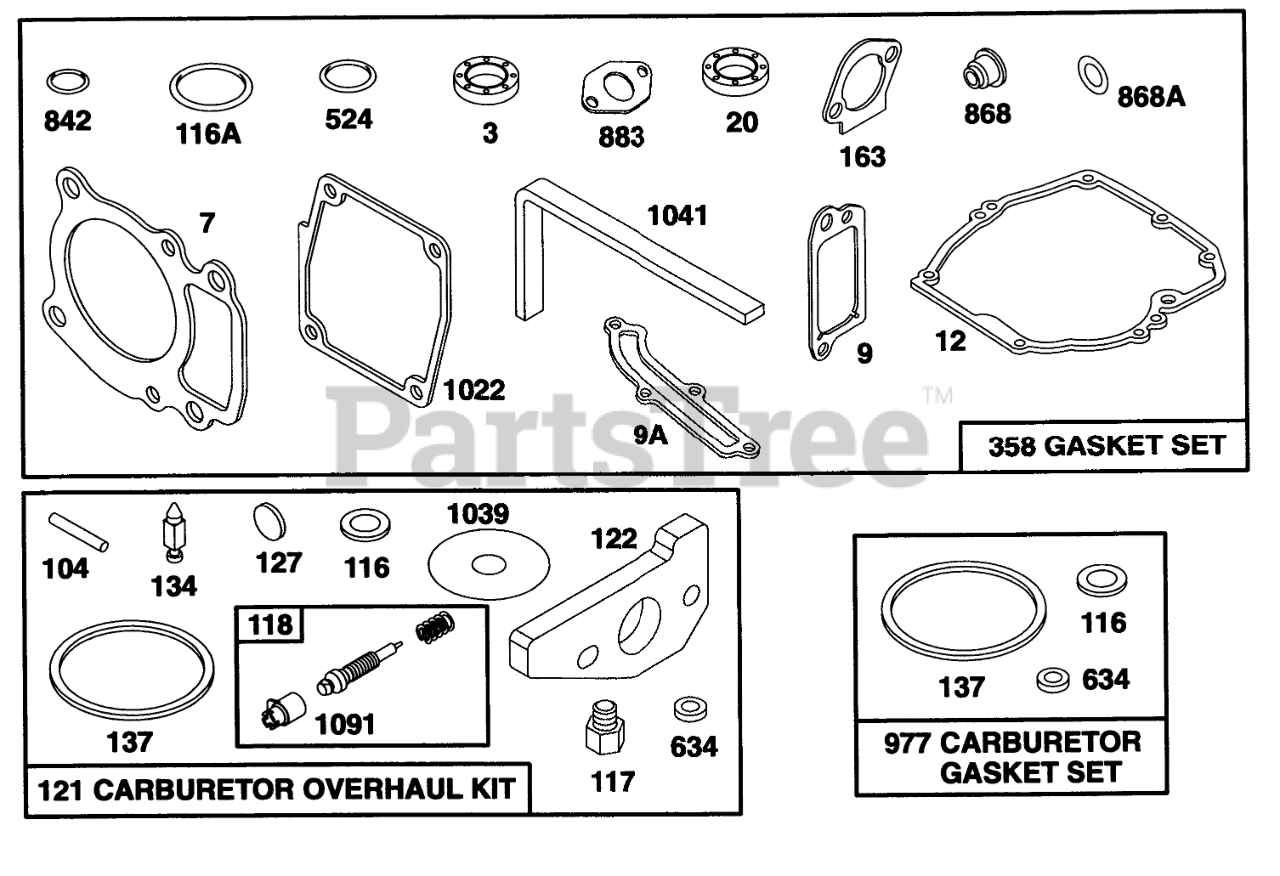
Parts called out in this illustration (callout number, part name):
3	SEAL - OIL
7	CYLINDER HEAD GASKET
9	BREATHER GASKET
9A	GASKET-BREATHER
12	ENGINE BASE GASKET
20	SEAL-OIL
104	FLOAT HINGE PIN
116	SEALING GASKET
116A	O RING SEAL
118	VALVE/SPRING - NEEDLE
121	KIT-CARBURETOR OVERHAUL
122	ADAPTER ASSEMBLY
127	PLUG - WELCH
134	Valve-Inlet (Includes Seat)
137	FLOAT BOWL GASKET
163	AIR CLEANER GASKET
358	GASKET SET
524	O-RING
634	SEAL WASHER
842	O-RING
868	SealAssy-Valve
868A	Seal-Valve
883	EXHAUST GASKET
977	CARBURATOR GASKET SET
1022	ROCKER COVER GASKET
1039	FLOAT LIMITER
1041	SEAL - FOAM
1091	CAP - LIMITER
